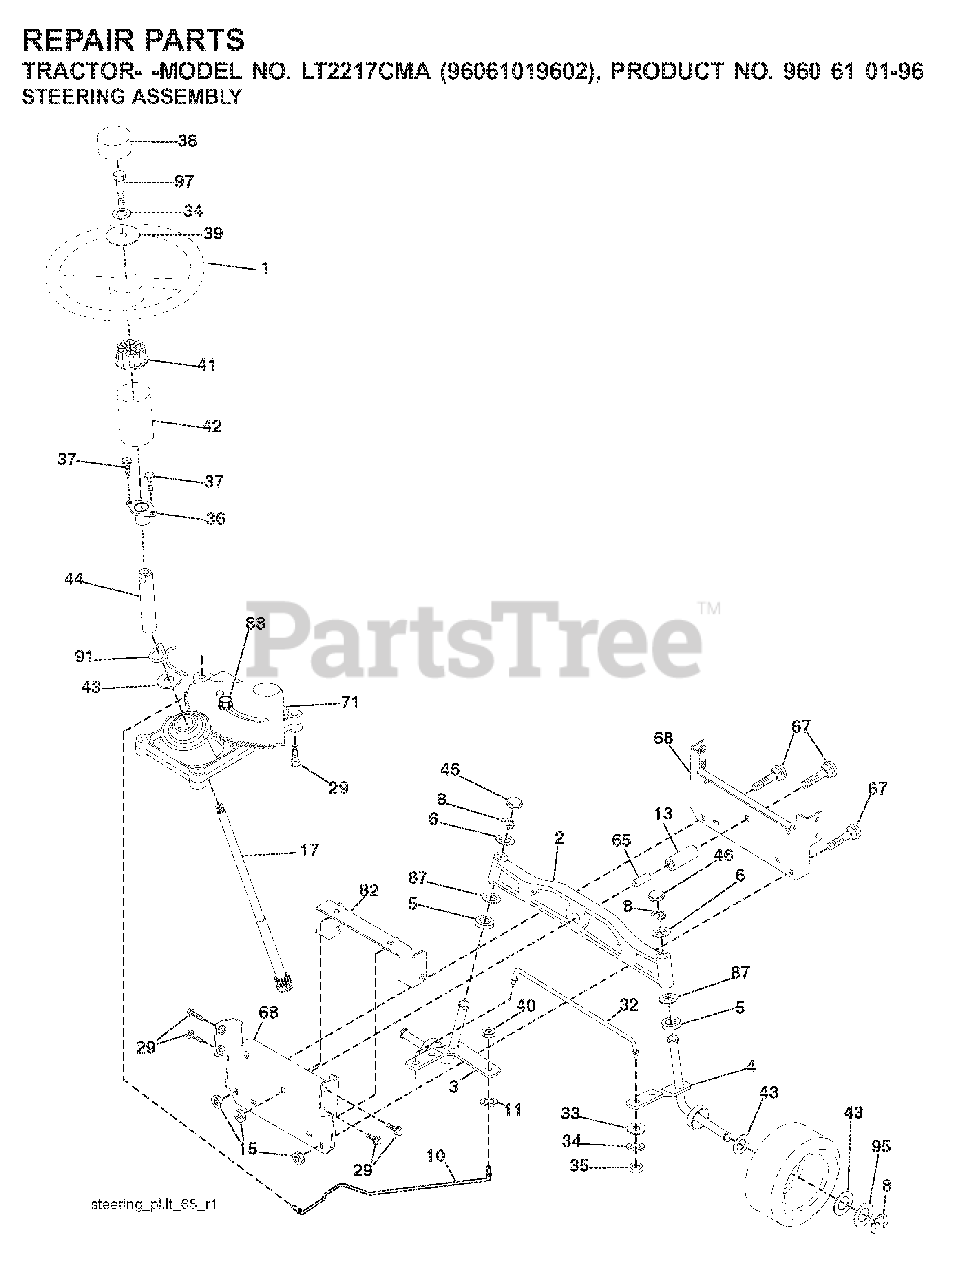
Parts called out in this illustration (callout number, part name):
1	WHEEL.STEERING.PREM.2.BLK
2	AXLE ASSY FRONT
3	SPINDLE.ASM.LH.15"TIRES
4	SPINDLE.ASM.RH.15"TIRES
8	RING CLIP
10	DRAGLINK.15".TIRES.2001
11	WASHER, LOCK 3/8
13	TUBE, PIVOT AXLE
15	NUT
17	SHAFT STEERING SPLINE
29	SCREW, 3/8-16X3/4
32	ROD.ASM.TIE.BALL.JOINT.NOVAN
33	WASHER M
34	LOCKWASHER
35	NUT, CROWNLOCK
36	BUSHING, STEERING
38	INSERT.CAP.STRG.WH.BLACK
39	WASHER.11/32
40	NUT CROWNLOCK 3/8-24
41	ADAPTER, WHEEL STNG..
42	BOOT.STEERING.SHAFT.BLACK
44	SHAFT.EXTEN.STRG.SPLINE
46	CAP.SPINDLE
65	SPACER BRACE AXLE
67	BOLT CARRIAGE
68	BRACE.AXLE.15"TIRES
71	STEERING ASM
82	BRACKET.SUSP.CHASSIS.FRONT.15
87	WASHER, FLAT .781 X 1 1/2"
88	BOLT, SHOULDER 7/16-20
91	CLIP.STEERING
95	WASHER.HARDENED
